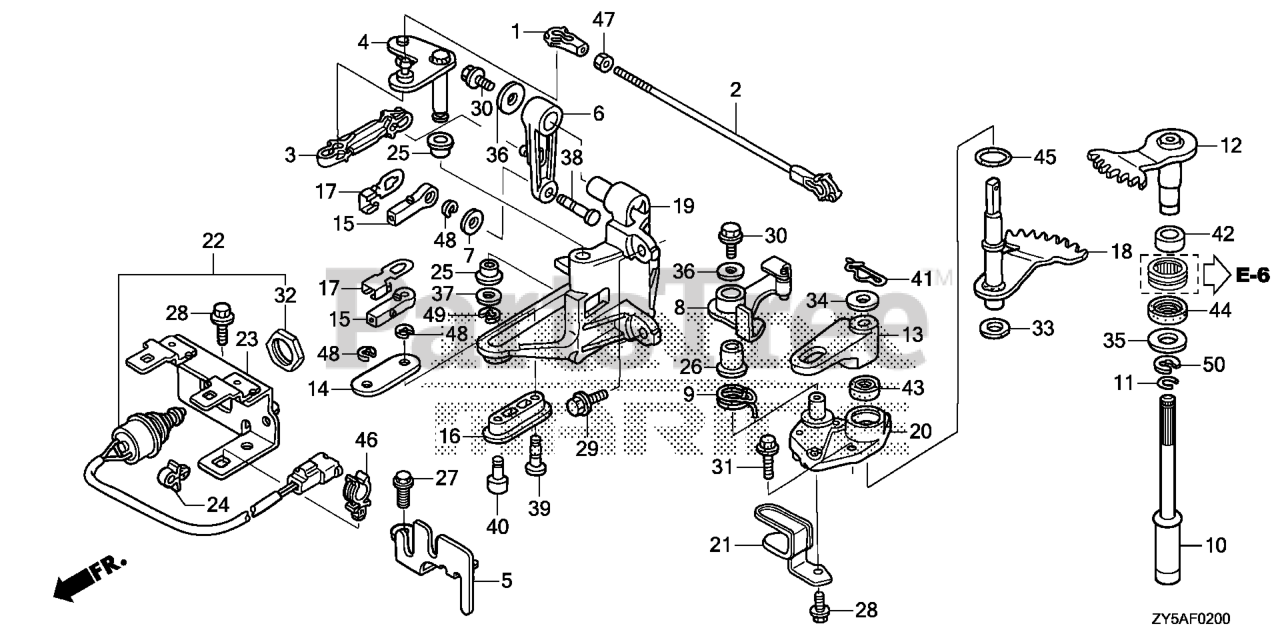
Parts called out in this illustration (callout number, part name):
1	LINKAGE, PIVOT
2	ROD, THROTTLE
3	LINK, THROTTLE
4	PLATE, THROTTLE
5	PLATE, REMOTE CONTROL CABLE
6	ARM, THROTTLE
7	WASHER, PIVOT
8	ARM, CLICK
9	SPRING, CLICK
10	ROD A, SHIFT (XL)
11	RING, STOPPER
12	SHAFT A, SHIFT
13	ARM, SHIFT
14	PLATE, SHIFT PIVOT
15	PIVOT, SHIFT
16	PIVOT, SHIFT SLIDE
17	PLATE, LOCK
18	SHAFT B, SHIFT
19	BRACKET, SHIFT LINK
20	HOLDER, SEAL *NH8* (DARK GRAY)
21	BRACKET A, CABLE
22	SWITCH ASSY., NEUTRAL
23	BRACKET, NEUTRAL SWITCH
24	CLIP, BRAKE PIPE (A) (FOR NEUTRAL SWITCH)
25	BUSH A, COVER LOCK
26	BUSH, BLADE BRAKE
27	BOLT, FLANGE (6X16)
28	BOLT, FLANGE (6X14)
29	BOLT, FLANGE (6X18)
30	BOLT, FLANGE (6X12) Use from Frame SN 1005249.
31	BOLT, FLANGE (6X20) (ENGINE NO.)
32	NUT, HEX. (20MM) Use up to Frame SN 1300359.
33	WASHER B, THRUST (14MM)
33	WASHER, SHIFT SHAFT
34	WASHER, PLAIN (12MM)
36	WASHER, PLAIN (6MM)
37	WASHER, PLAIN (8MM) Use from Frame SN 4800713.
39	PIN, SHIFT LINK
41	PIN, SNAP (12MM)
42	RING (INNER) (15X20X13)
43	OIL SEAL (14X26X6)
44	SEAL, WATER (14X26X8)
45	O-RING (25X2.4) (NOK)
46	HOLDER, DRAIN TUBE
47	NUT, HEX. (5MM)
48	E-RING (4MM)
49	E-RING (6MM)
50	E-RING (12MM)
